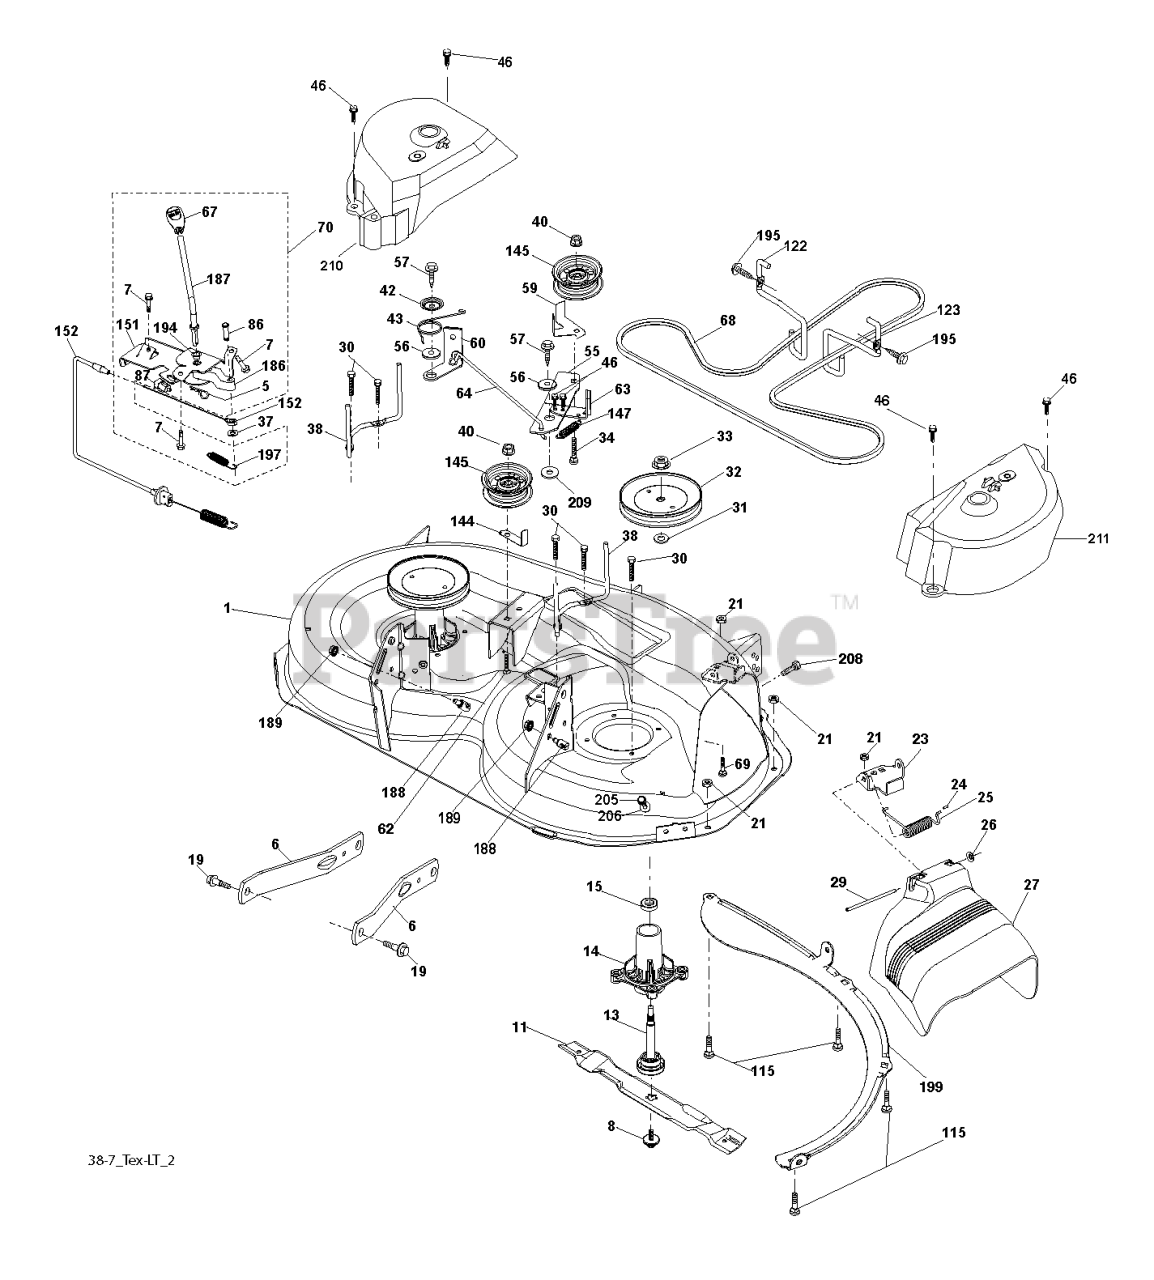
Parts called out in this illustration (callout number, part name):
1	HOUSING
5	RETAINER-SPRNG RB
6	ARM.SUSPENSION.MOWER.R
7	SCREW
8	BOLT.WASHER.ASM.7/16-2
11	BLADE 38" PREMIUM
13	SHAFT.ASM.MDRL.N/GREASE.38
14	RP.HOUSING.MANDREL.4PT.
19	BOLT.SHOULDER
21	LOCKNUT
23	BRKT.DEFLECTOR.38"2005+
24	CAP-SLEEVE LT
25	SPRING.TORSION.DEFLECT
26	NUT PUSH M
27	SHIELD ASM.DFLCTR MWR.38-7"BLK
29	ROD.HINGE
30	SCREW, WASHER HEAD
31	WASHER.SPACER.MANDREL
32	PULLEY.MANDREL.5.0.PD.38"
33	NUT.FLANGE.LOCK.TOP
34	BOLT.3/8-16X1.50
37	WASHER
38	KEEPER BELT LH MANDREL
40	NUT LOCK FLG 3/8-16 UNC
42	SPRING.TORSION.BRAKE
43	SRPING.TORSION.RETAINE
46	SCREW.1/4-20X5/8
56	SPACER.RETAINER
57	SCREW 3/8-16X1
59	GUARD, BELT
60	ARM BRAKE MOWER RH 38"
62	BOLT.3/8-16X1.50
63	RP ARM.BRAKE.MOWER.38"LH.TEX
64	LINK BRAKE
67	HANDLE.CLUTCH.CABLE.LT
69	BOLT
70	CLUTCH.ASM.MANUAL.LT.PRED
86	PIN ATTACHMENT CABLE
87	SWITCH.INTRLCK.CLUTCH.
115	BOLT.CARR.5/16-18X5/8.SHORT
122	KEEPER BELT ENGINE LH
123	KEEPER BELT RH
144	KEEPER, BELT IDLER
145	PULLEY.IDLER.48"PRIMARY
147	SPRING RETURN
151	BRACKET.CLUTCH CBL.PRED LT
152	CLUTCH CABLE
186	ARM ACTUATOR
187	LEVER.CONTROL.CL.CABLE.PRED LT
188	STUD.FASTNER.W/ANTI-ROTATE
189	NUT LOCK HEX FLANGE 5/16-18
194	BEARING.CONTROL.LEVER.CLUTCH
195	SCREW, 3/8-16X3/4
197	SPRING.PLUNGER.ACTUATOR
199	BAFFLE.VORTEX.FRONT.38"
205	SCREW
208	SCREW 3/8-16X1/2
209	WASHER 12/32X2X10GA
